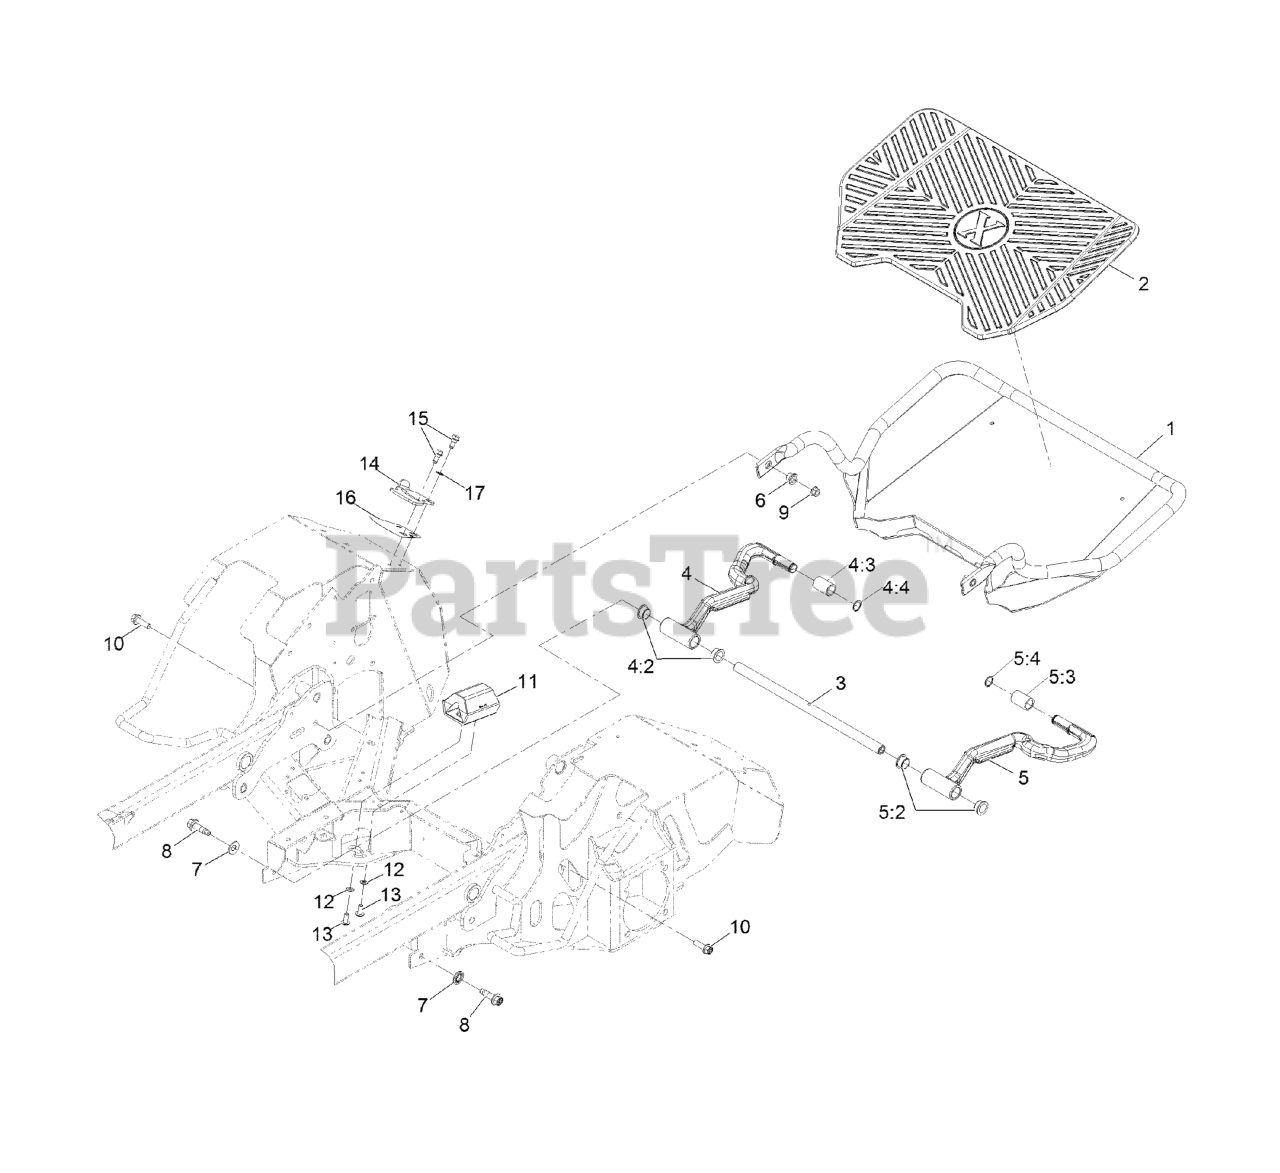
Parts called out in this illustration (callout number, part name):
1	WELD, PLATFORM
2	MAT, PLATFORM
3	SHAFT, CROSS
4	ASM, RT ARM W/ BUSHINGS
4:2	BUSHING-FLANGE
4:3	Bushing, Sleeve
4:4	RING-SNAP
5	ASM, LT ARM W/ BUSHINGS
5:2	BUSHING-FLANGE
5:3	Bushing, Sleeve
5:4	RING-SNAP
6	BUSHING-FLANGED
7	WASHER-SPRING
8	SCREW-HHF
10	SCREW, HHF
12	WASHER-LOCK
13	SCREW-TORX
14	LATCH, PLATFORM
15	SCREW-SHOULDER
16	DECAL-LATCH LOCK
17	WASHER, PLASTIC
17	Washer, Wave
